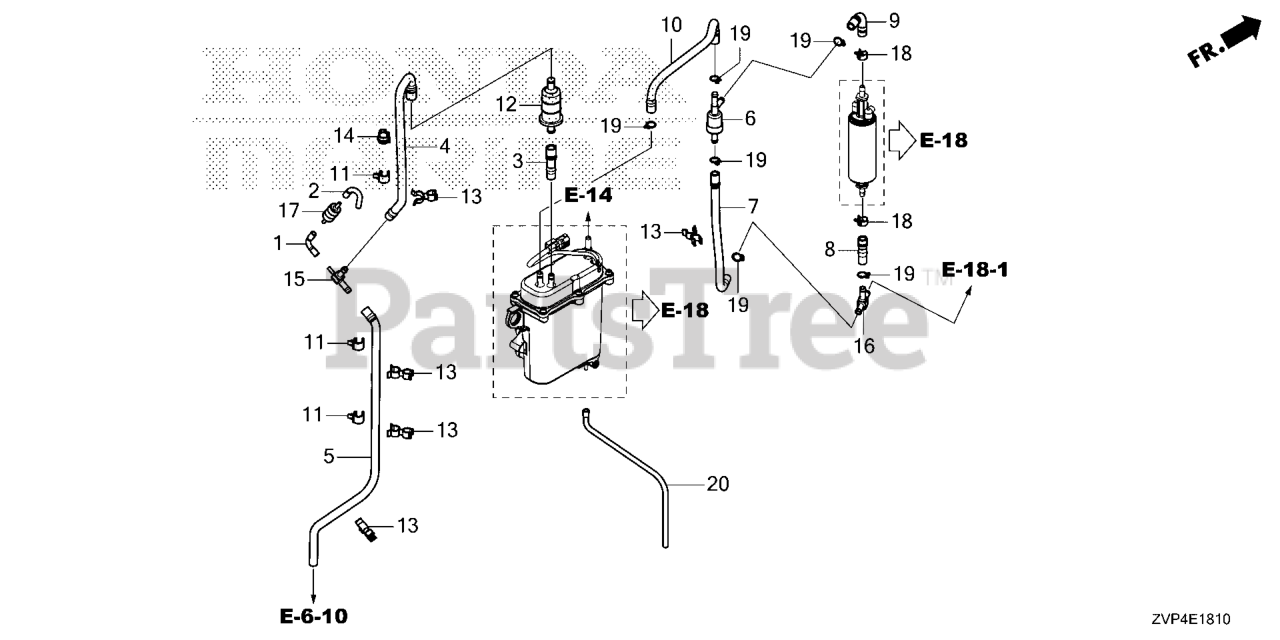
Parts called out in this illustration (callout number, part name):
1	TUBE C, AIR VENT
2	TUBE B, CHECK VALVE
3	TUBE A, AIR VENT
4	TUBE COMP B
5	TUBE COMP C
6	VALVE COMP, RELIEF
7	TUBE, RELIEF
8	TUBE C, FUEL
9	TUBE D, FUEL
10	TUBE E, FUEL
11	CLAMP B, FUEL TUBE
12	FILTER, FUEL PUMP
13	CLAMP, HOSE
14	CLAMP, PIPE
16	JOINT, THREE WAY
17	VALVE, CHECK
18	CLAMP, TUBE (D12)
19	CLIP, TUBE (B12)
20	BULK HOSE, VINYL (3.5X6.5X8000) (9500(95003-05001-60M) (CARBURETOR NO.)
